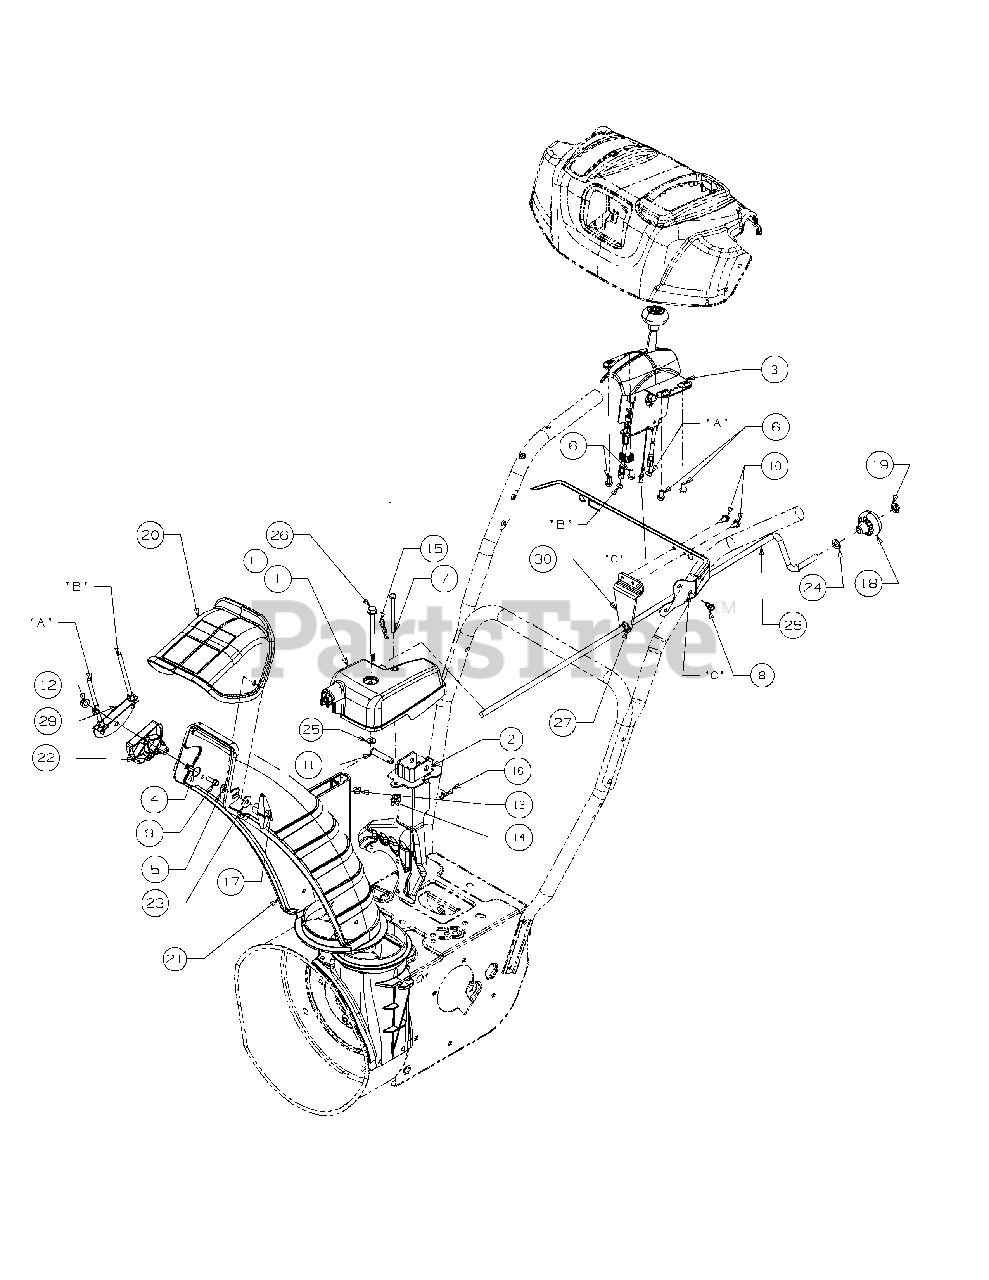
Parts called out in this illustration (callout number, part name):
1	Gearbox Asm-Wo
2	Bracket A
3	Control Assy-C
4	Bolt-Carriage 5/16
5	Bolt-Carriage 5/
6	Screw-Hex
7	Screw-Hex Cap 1/4
8	Screw-Hex Wash Sf
9	Screw-Hex Tap 1/4
10	Screw Hex.Wash.Hd
11	Pin:Clevis
12	Nut-Flglk 5/16-18
13	Nut-Flglk
14	Nut, Wing-1/4-20
15	Pin-Intern Cot-1
16	Pin-Cotter
17	Knob-Wing Nut
18	Knob-Shift Snow
19	Nut-Push
20	Chute-Upper:W/
21	Chute-Lower 5" Dia
22	Guide-Cable Chute
23	Washer-Fl
24	Washer-Fl
25	Washer-Flat Hrdn
26	Screw-Shoulder Flg
27	Bushing .380 Id
28	Crank-Chut
29	Bracket-Cable
30	Bracket-Rod Suppor
